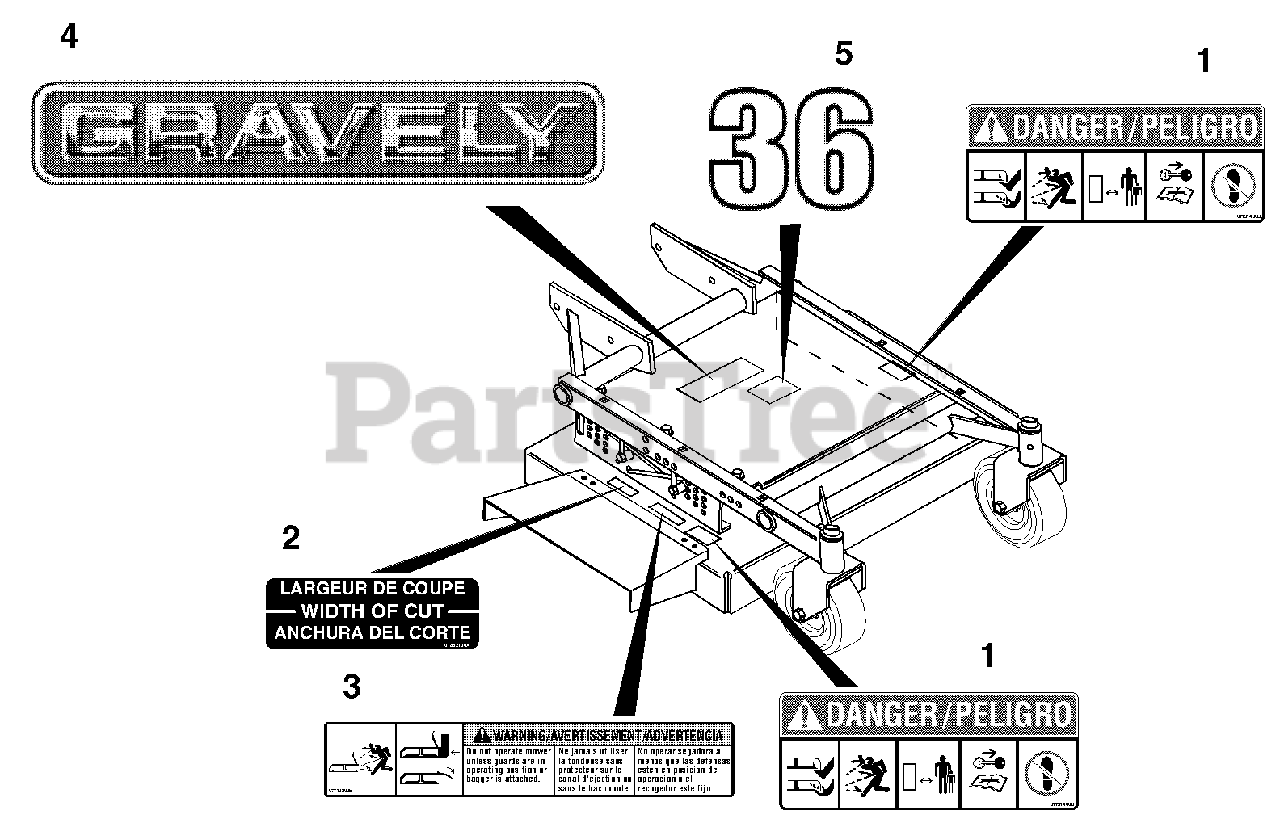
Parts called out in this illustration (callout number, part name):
1	Decal, Mower Pan Head Danger
2	Decal, Width of Cut
3	Decal, Warning
4	Decal- 15" Gravely Logo
5	Decal-36"
